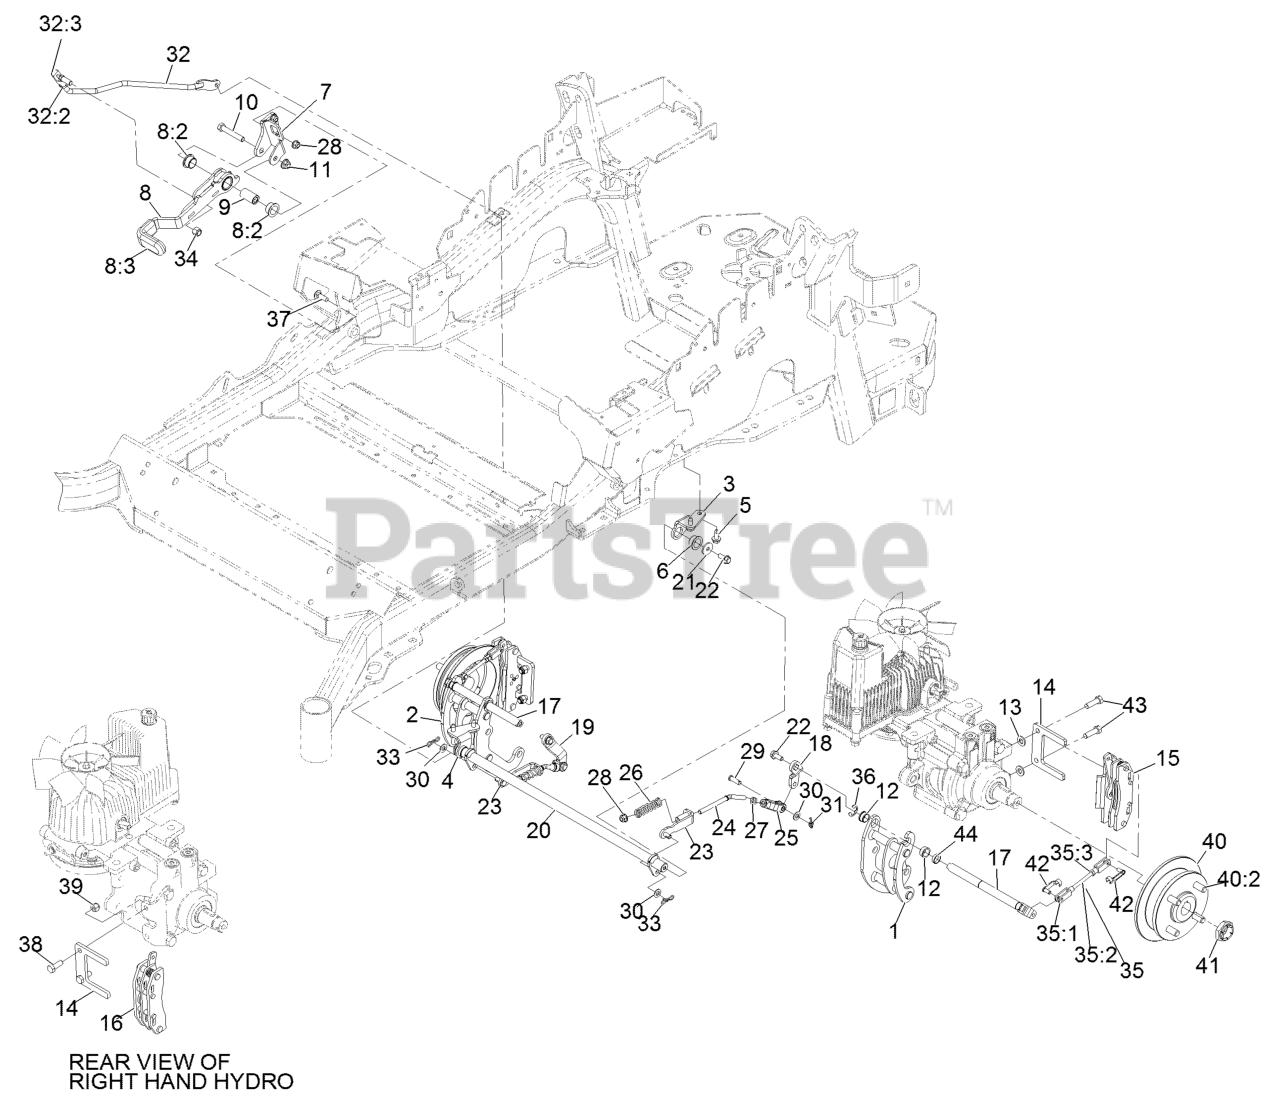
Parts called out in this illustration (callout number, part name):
1	Mount-Bellcrank, LH
2	Mount-Bellcrank, RH
3	Mount-Pivot, LH
4	Mount-Pivot, RH
5	Screw-HWH 5/16-18 X 3/4 Tf
6	Bushing-Flanged
7	Bracket-Mount
8	Brake Lever ASM
8:2	Bushing-Flanged
8:3	Grip-Lever
9	Handle-Pivot, Brake
10	Screw-HH 3/8-16 X 2 1/4
11	Nut-Nyloc 3/8-16 Flg
12	Bushing-Igus
13	Washer-3/8 Sae
14	Plate-Mount, Brake
15	Caliper-Brake
16	Caliper-Brake, RH
17	Bellcrank
18	Arm-Inner, LH
19	Arm-Inner, RH
20	Shaft-Cross
21	Washer-Flat
23	Bracket-L
24	Linkage-Mid
25	Yoke-Offset
26	Spring-Compression
27	Nut-Jam 5/16-24
28	Nut-Nyloc 5/16-18 Flg
29	Pin-Clevis 5/16 X 1 49/64
30	Washer-5/16 Sae
31	Pin-Cotter, Locking
32	Front Linkage ASM
32:2	End-Tie Rod, RH
32:3	Nut-Jam 3/8-24
33	Pin-Cotter, Locking
34	Nut-Nyloc 3/8-24
35	Rear Linkage ASM
35:1	Yoke
35:2	Linkage, Rear
35:3	Nut-Jam 1/4-28
37	Bolt-Carriage 5/16-18 X 1
38	Screw-HH 3/8-16 X 1
39	Nut-Nyloc 3/8-16
40	Wheel Hub ASM
40:2	Stud-Wheel
41	Locknut
42	Pin-Clevis, Spring
43	Screw-HH 3/8-16 X 1 1/4 Patch Lock
